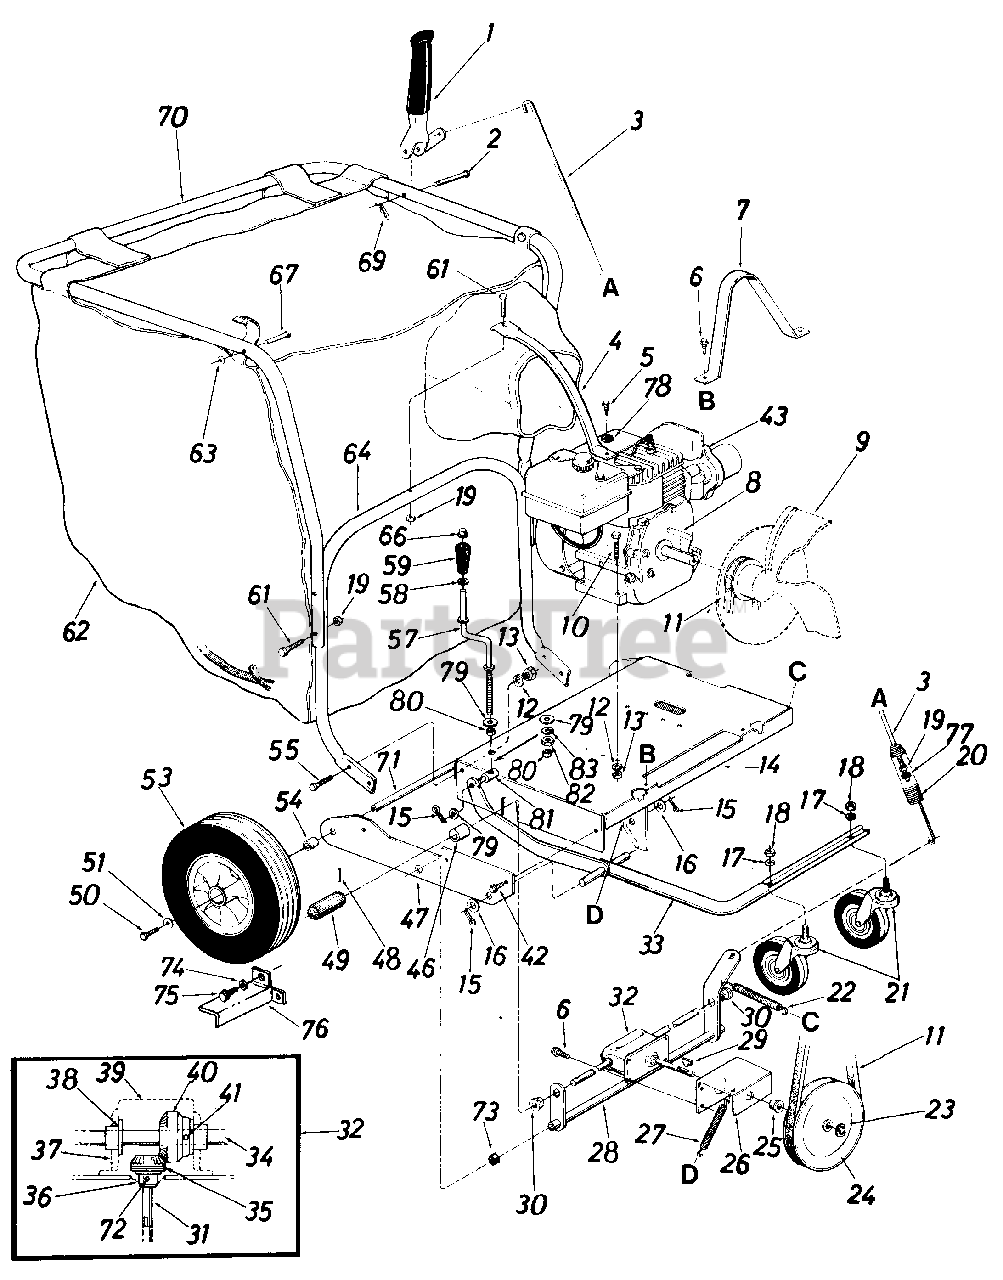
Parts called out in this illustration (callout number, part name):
1	Clutch Grip Ass'y.
2	Clevis Pin .375" Dia. x 1.88"
3	Clutch Rod 32" Lg.
4	Handle Brace (Painted)
5	Part of Engine
6	Hex L-Wash. Hd. AB Tap Scr. 1/4" x .62" Lg.
9	Air Vane Plate Ass'y.
11	"V"-Belt 1/2" x 26" Lg.
12	L.-Wash. 5/16" I.D.
13	Hex Nut 5/16-18 Thd.
16	Fl.-Wash. .63" I.D. x 1.25" 0. D.
17	L.-Wash . 1/2 " 1. D.
18	Hex Nut 1/2-13Thd.
19	Hex Cent. L.-Nut 1/4-20 Thd.
20	Extension Spring .78" O.D. x .75" Lg.
21	Swivel Caster Wheel 5" Dia. x 1.25"
22	Extension Spring .38" O.D. x 7.50" Lg.
23	Snap "E"-Ring.50" Dia. Shaft
24	"V"-Pulley 5/8" x 6.50" O.D.
25	Flange Bearing .502" I.D.
28	Clutch Bracket Ass'y.
29	#2 Woodruff Key 3/32" Dia. x.81" Lg.
30	Hex Flange Bearing Bronze .625 " I.D.
31	Pinion Shaft .50" Dia. x 5.0"
32	Gear Box Ass'y. Comp.
35	Bevel Gear .50" I.D. x 14 Teeth
36	Flange Bearing .503" I.D.
37	Gear Box
38	Flange Bearing .630" I.D.
39	Gear Box Cover
40	Bevel Gear .62" I.D. x 28
41	Spring Pin Spiral 3/16" Dia. x 1.25 Lg.
42	Hex Wash. Hd. "AB" Tap Scr. 5/16" x .75" Lg.
43	Engine
46	Spacer .63 I.D. x .88" O.D. x.56" Lg.
49	Drive Pinion
50	Hex Locking Bolt 5/16-24 x.62" Lg.
51	Fl.-Wash. .34" I.D. x .87" O.D.
53	Wheel Ass'y. - Comp. 12" x 3"
54	Spacer .63" I.D. x 1.00" O.D. x.94" Lg.
55	Hex Bolt 5/16-18 x .75" Lg.
57	Height Adjustment Crank
58	Fl.-Wash. 138" I.D. x .62" O.D
59	Crank Knob
61	Hex Bolt 1/4-20 x 1.75" Lg.
62	Vacuum Bag- Felt
63	Push Speed Nut .25" Dia. Stud
66	Push Nut 3/8" Dia.
67	Stud Pin .250" Dia. x 1.75"
69	Internal Cotter Pin 3/8" Dia.
70	Upper Handle (Painted)
71	Rear Axle .624" Dia. x 24.37"
72	Spring Roll Pin 5/32" Dia. x 1.12
73	Spacer .82" I.D. x 1.00" O.D. x .305 Lg.
74	L.-Wash. .265" I.D.
75	Hex Self Tap Scr. 1/4" x 3/8" Lg.
78	Belleville Washer
79	Fl.-Wash . .35 " I . D. x .87 " O . D.
80	Spacer .38" 1 .D. x .50" O.D. x .180" Lg.
81	Ferrule 3/8-8 x .38" Dia.
82	Hex Nut 3/8-8 Thd.
83	L.-Wash. 3/8" I.D.
